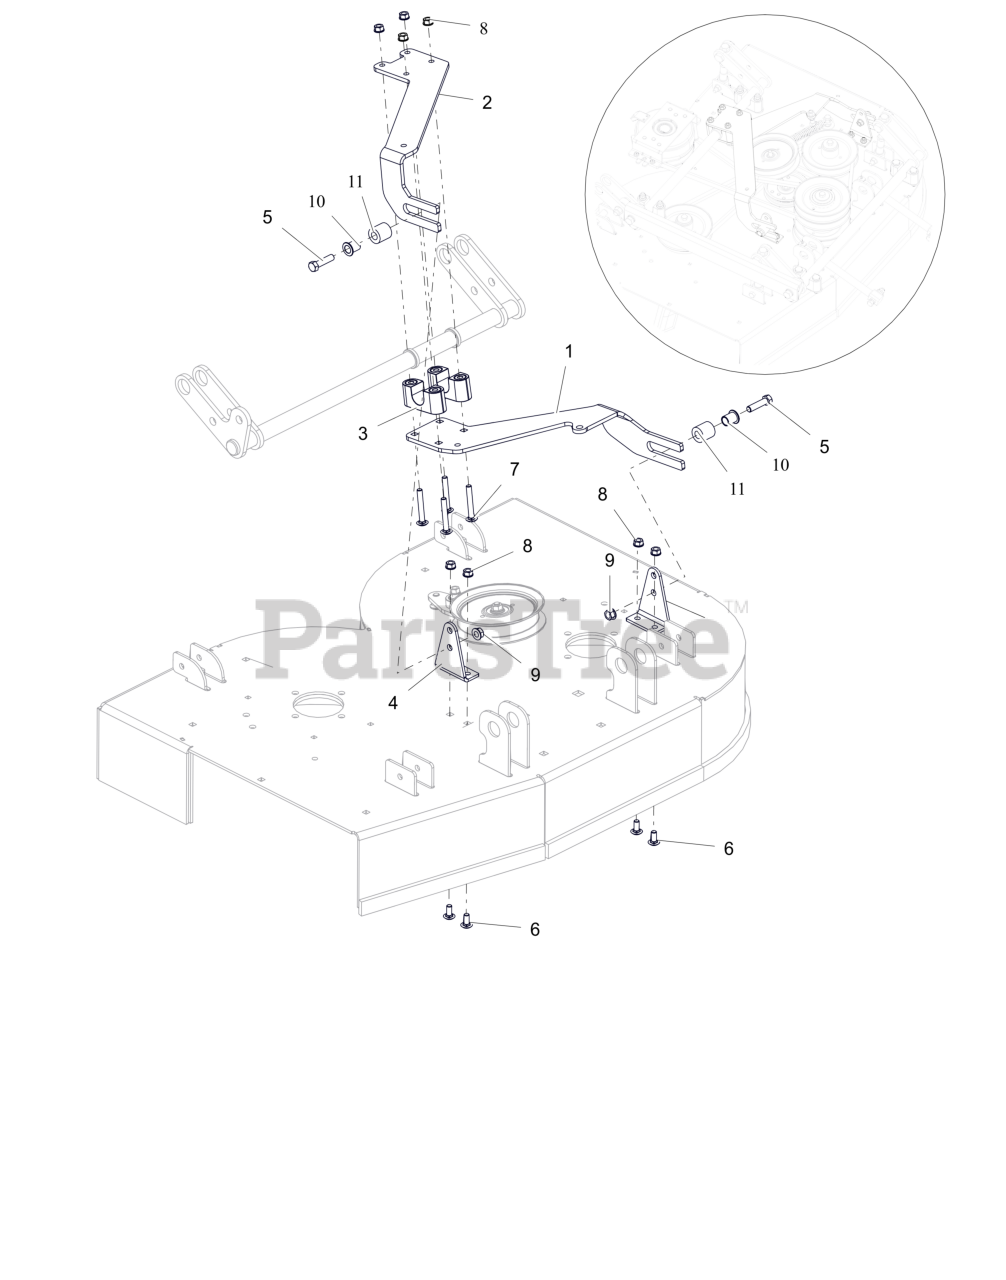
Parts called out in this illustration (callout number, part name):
1	BRKT, PIVOTING IDLER (BLACK)
2	BRKT, UPPER PIVOTING IDLER (BLACK)
3	ASM-BUSHING, DECK LIFT
4	BRKT, IDLER PIVOT (BLACK)
5	BLT, HEX .38-16X1.50 G5 ZCC
6	BLT, RHSSN.31-18X.750 G5 ZCC
7	BLT, RHSSN.31-18X2.25 G5 ZCC
8	NUT,LK-CTR-FLG .31-18 GF ZCC
9	NUT-LK-CTR-FLG .375-16 GF ZCC
10	BSHG- FLANGE .5X.625X.75X.062
11	SPCR- SLV .385 X .500 X .750
